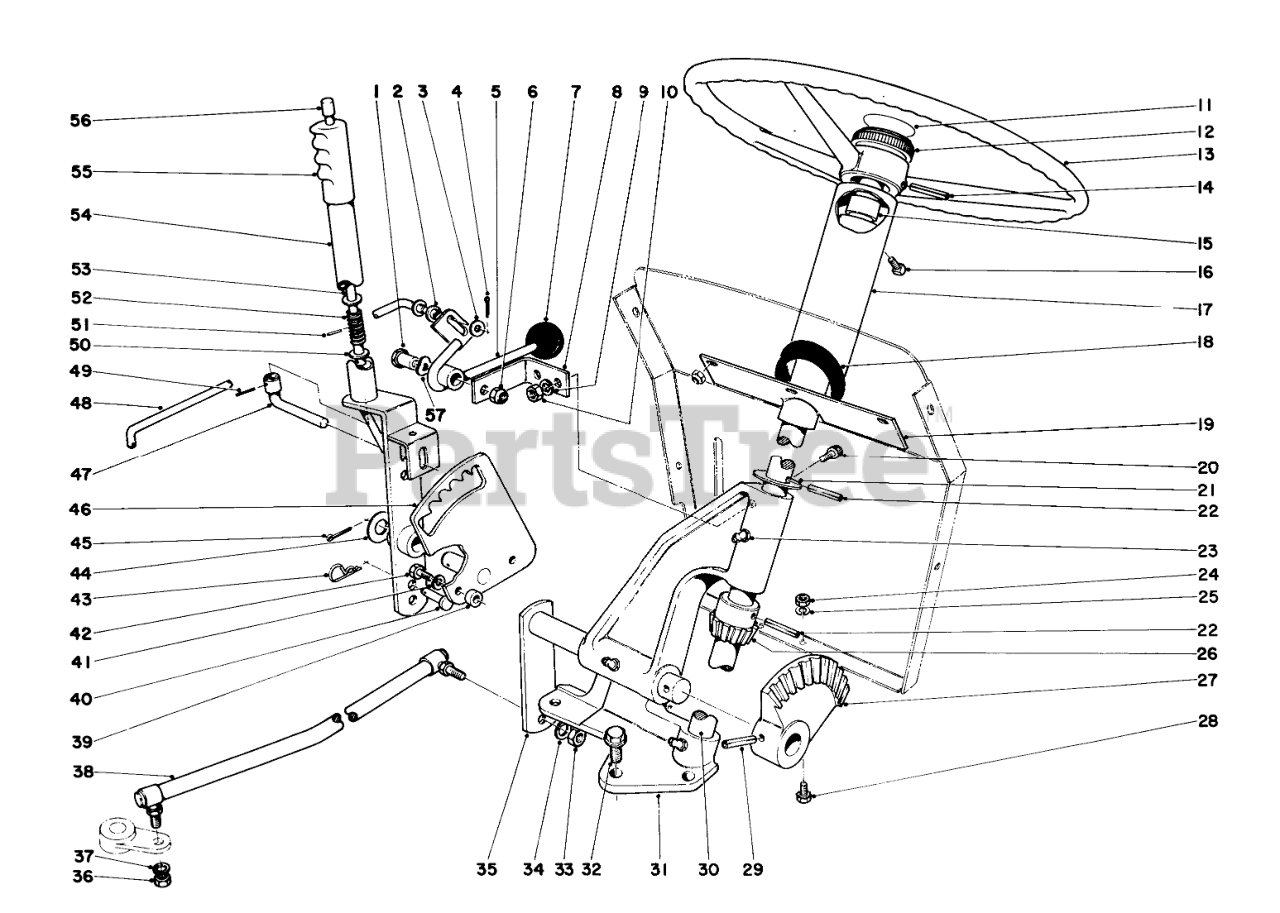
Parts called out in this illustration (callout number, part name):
1	Shoulder Bolt
2	Bushing
3	WASHER-FLAT
4	PIN-COTTER
5	Clutch Lever
6	Nut
7	Knob
8	Idler Bracket
9	WASHER-LOCK/SP
10	NUT-HEX
11	Decal Steering Cap
12	Steering Cap
13	Steering Wheel
14	Roll Pin
15	BUSHING
16	SCREW-SQH
17	Cover Steering Support
18	Grommet
19	Steering Tube Incl. Ref. No. 15
20	Screw
21	WASHER-FLAT
22	PIN-ROLL, SLOTTED
23	Grease Fitting
24	NUT-HEX
25	WASHER-LOCK
26	Pinion Gear
27	Steering Gear
28	Sems Screw
29	1/4 X 2 DRIVELOK PIN
30	Steering Shaft
31	Steering Gear Support
32	Screw-HH
33	NUT-HEX
34	WASHER-LOCK
35	Steering W.A.
36	NUT-HJ
37	WASHER-LOCK
38	Steering Rod
39	Spacer
40	Pin
41	WASHER-LOCK
42	SCREW-HH
43	PIN-COTTER, HAIR
44	Washer
45	PIN-COTTER
46	Quadrant
47	Lift Lock
48	Clutch Rod
49	PIN-SPRING
50	Washer
51	Roll Pin
52	Spring
53	Lift Rod
54	Lower Handle
55	Handle Grip
57	Wavy Washer
